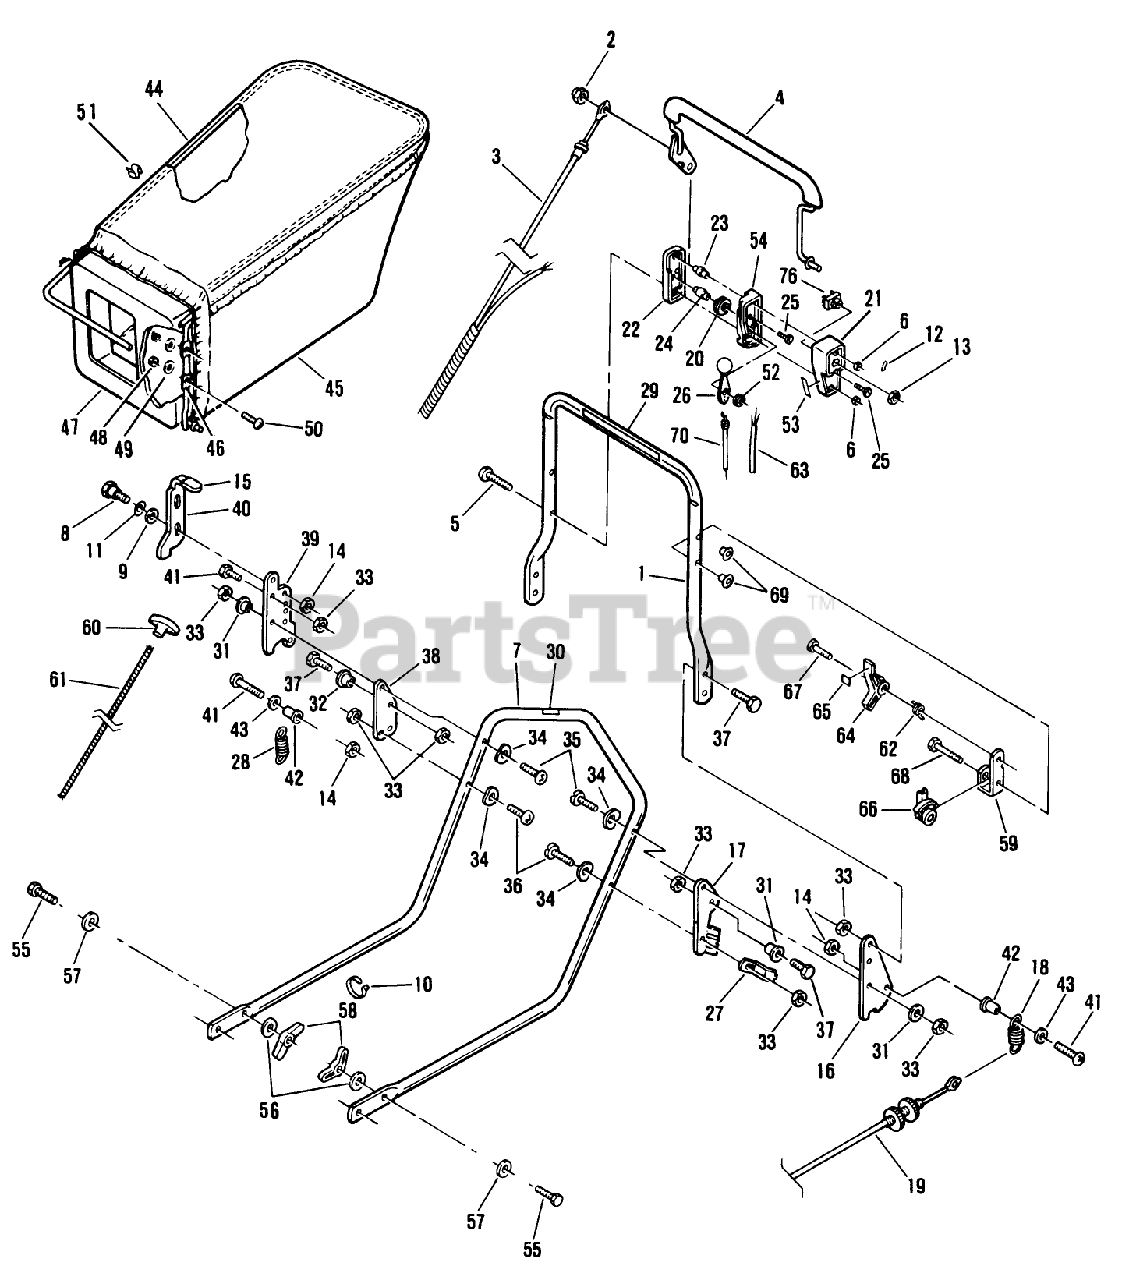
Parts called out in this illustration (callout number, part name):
2	NUT ACORN
3	CONTROL CABLE WES
5	SCREW
6	NUT C/LOCK E
8	BOLT RB&W
9	WASHER M
14	LOCKNUT E
15	KNOB (S&R)
18	SPRING
19	CABLE AY
20	PULLEY PL
23	COLUMN
24	PIN SKF
25	SCREW
26	LEVER&KNOB AY WES
29	Decal-Drive Control
33	NUT-LOCK F
34	WASHER-CURVED
35	SCREW LARSON
42	SPACER ROCKFORD
43	WASHER
44	HANGER BAG TROX
47	BAG ADAPTOR PL
48	LOCKNUT E
49	WASHER
51	S CLIP ARDEN
52	WASHER-SPRING
57	WASHER
58	NUT-WING
68	BOLT QUALITY
70	CABLE TH'TTLE WES
